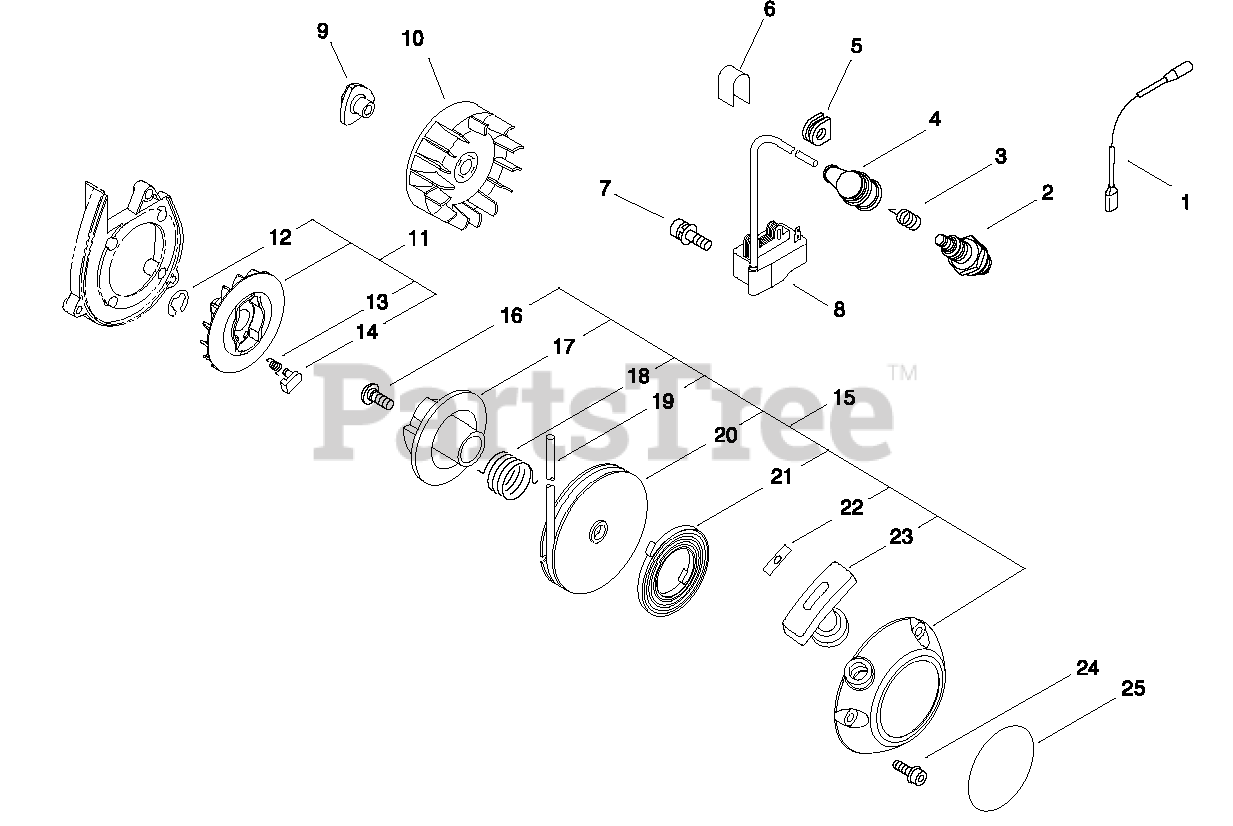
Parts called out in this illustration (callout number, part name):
1	LEAD - IGNITION
2	SPARK PLUG -- BPM-8Y
3	TERMINAL, SPARK PLUG CAP
4	CAP, SPARK PLUG
6	LABEL - SPARK PLUG -- BPM-8Y
7	SCREW - 4X20
8	COIL, IGNITION
9	HUB, FAN
10	FLYWHEEL
11	STARTER PAWL ASSY
12	RING, RETAINING - 4
13	SPRING
14	PAWL, STARTER
15	STARTER ASSY
16	SCREW
17	PLATE, CAM
18	SPRING,DAMPER
20	REEL, ROPE
21	SPRING, REWIND
22	RETAINER, ROPE
23	GRIP, STARTER
24	SCREW - 5X16
25	LABEL - ECHO
